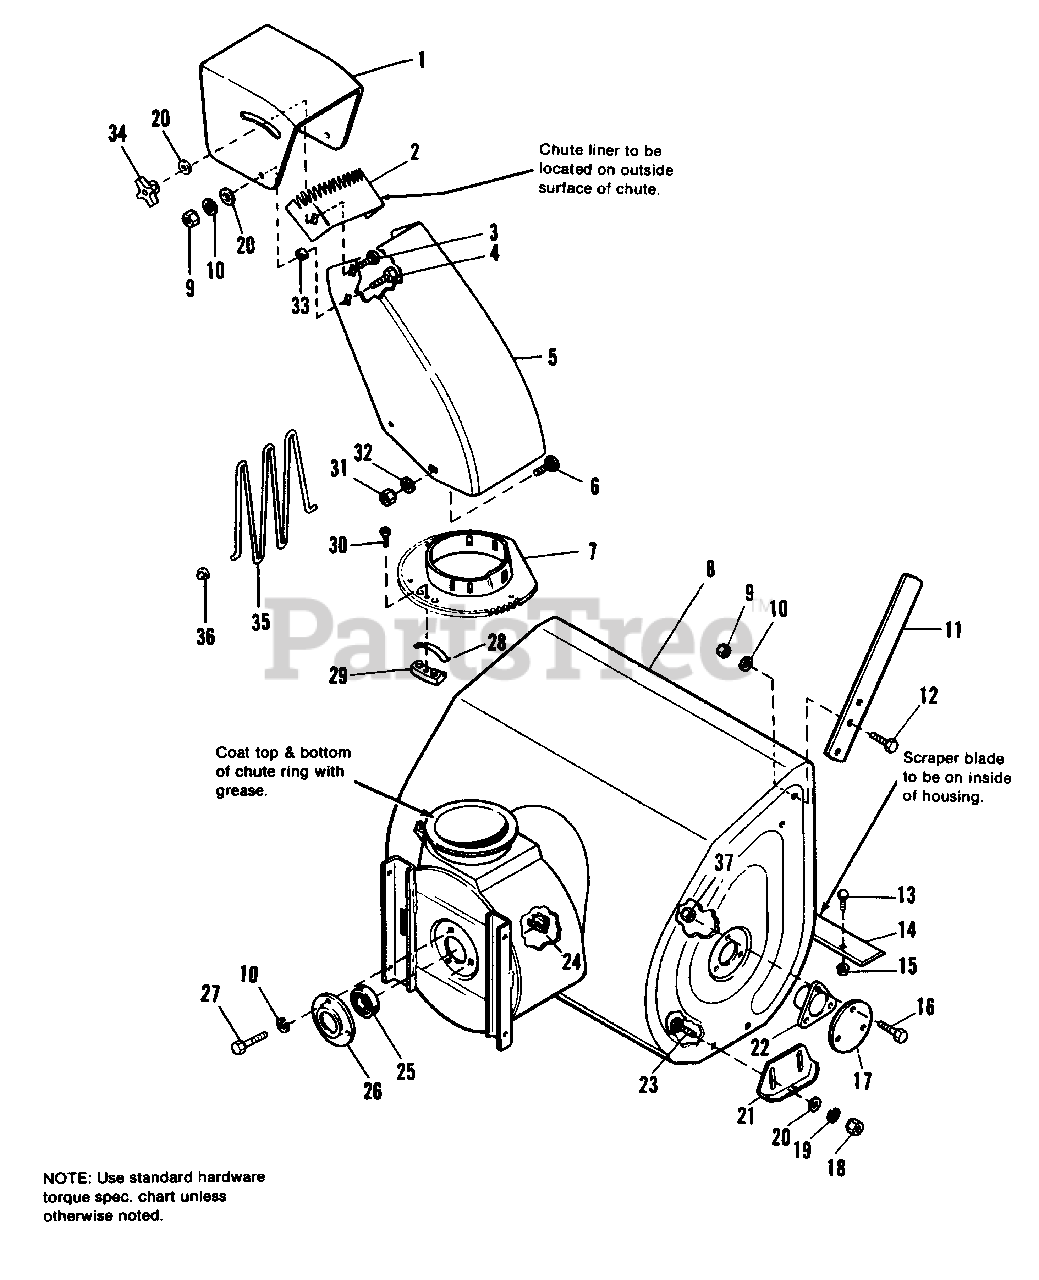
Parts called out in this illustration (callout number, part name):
1	DEFLECTOR ASSY.
2	LINER, Chute
3	BOLT, Carriage, 5/16-18 x 7/8
4	SCREW, Truss Phil Hd., 5/16-18 x 3/4
5	CHUTE
6	BOLT, Carriage, 1/4-20 x 5/8
7	GEAR, Chute
8	HOUSING ASSY., Auger, 60 cm (24")(Used on Mfg. No. 1690543, 1690544, 1690775, 1690903, 1691023)
8	HOUSING ASSY., Auger, 70 cm (28")(Used on Mfg. No. 1690545, 1690678, 1690776, 1690778)
8	HOUSING ASSY., Auger, 80 cm (32")(Used on Mfg. No. 1690546, 1690679, 1690777, 1690779)
9	NUT, 5/16-18 (Qty. 6, 8 & 10 HP only)
10	LOCKWASHER, 5/16 (Qty. 9, 8 & 10 HP only)
11	CUTTER, Drift (8 & 10 HP only)
12	CAPSCREW, Hex Hd., 5/16-18 x 3/4 (8 & 10 HP only)
13	BOLT, Carriage, 5/16-18 x 5/8 (Qty. 7, 10 HP only)
14	BLADE, Scraper, 60 cm (24")
14	BLADE, Scraper, 70 cm (28")
14	BLADE, Scraper, 80 cm (32")
15	LOCKNUT, Flange, 5/16-18 (Qty. 7, 10 HP only)
16	CAPSCREW, Hex Hd., 5/16-18 x 7/8
17	CAP, Bearing
18	NUT, Hex, 3/8-16
19	LOCKWASHER, 3/8
20	WASHER, Flat, 5/16
22	BEARING, Auger
23	BOLT, Carriage, 3/8-16 x 3/4
24	NUT, Retainer, 5/16-18
25	BEARING, Ball
26	RETAINER, Bearing
27	CAPSCREW, Hex Hd., 5/16-18 x 5/8
29	HOLD DOWN, Chute
30	SCREW, Plastite #10
31	LOCKNUT, Nylon, 1/4-20
32	WASHER, Flat, 1/4
34	KNOB, 4 Arm w/5/16-18 Thd. Insert
35	GUARD, Chute (Used on Mfg. No.1690775, 1690776, 1690777, 1690778, 1690779, 1690903, 1691023)
36	PUSHNUT (Used on Mfg. No. 1690775, 1690776, 1690777, 1690778, 1690779, 1690903, 1691023)
37	NUT, Hex, Center Lock, 5/16-18
